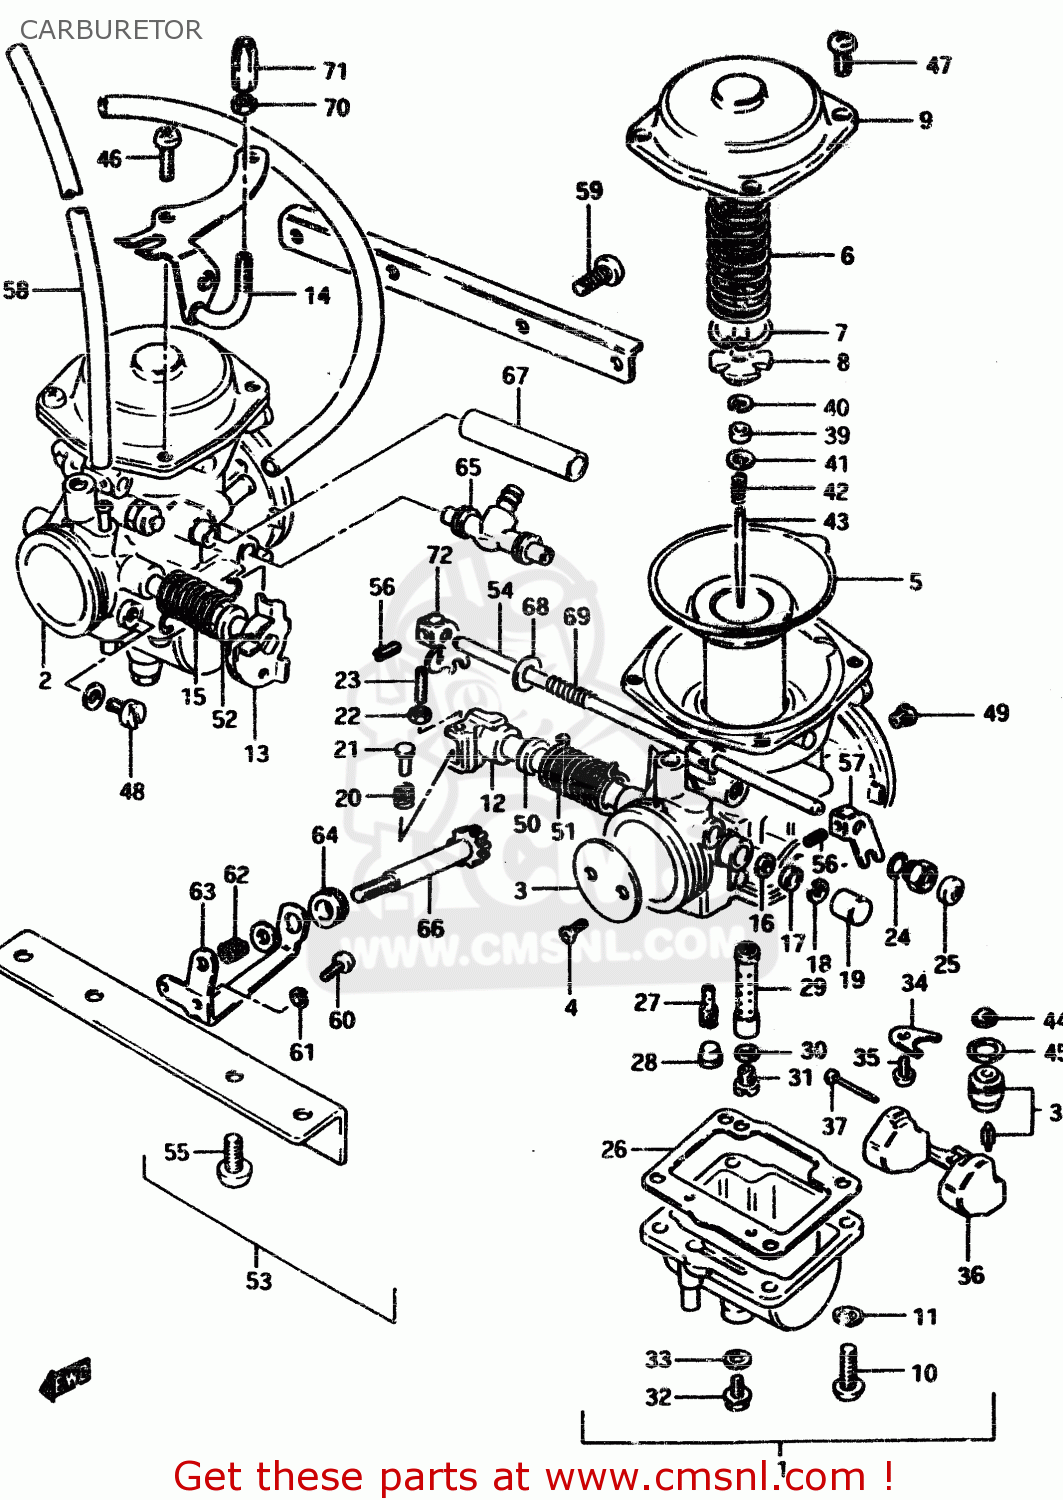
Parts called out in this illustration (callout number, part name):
1	CARBURETOR ASSY, LH
2	CARBURETOR ASSY, RH
3	VALVE, THROTTLE
4	SCREW
5	DIAPHRAGM ASSY
6	SPRING
7	E RING
8	HOLDER,GUIDE
9	COVER
10	SCREW
11	LOCK WASHER
12	SHAFT ASSEMBLY
13	SHAFT,THROTTLE
14	BRACKET,THROTTLE CABLE
15	SPRING
16	SEAL
17	GASKET,THROTTLE SHAFT (NAS)
18	E RING
19	CAP
20	SPRING,THROTTLE SCREW
21	PIN,THROTTLE LEVER
22	NUT
23	SCREW
24	O RING
25	CAP,STARTER VALVE
26	GASKET,FLOAT CHAMBER (NAS)
27	JET,PILOT(45)
28	PLUG,NEEDLE JET
29	JET, NEEDLE (0-9)
30	WASHER,NEEDLE NOZZLE
31	JET,MAIN(115)
32	PLUG,DRAIN
33	GASKET (NAS)
34	PLATE,NEEDLE VALVE FITING
35	SCREW 4X6
36	FLOAT
37	PIN,FLOAT
38	VALVE ASSEMBLY,NEEDLE
39	RING
40	CLIP
41	WASHER,JET NEEDLE
42	SPRING
43	NEEDLE, JET (5CDT61-3)
44	FILTER
45	O-RING,NEEDLE VALVE
46	SCREW
47	SCREW
48	SCREW
49	JET,AIR(140)
50	SPACER,THROTTLE SHAFT
51	SPRING
52	SPACER,THROTTLE SHAFT
53	FLANGE ASSEMBLY,CARBURETOR
54	SHAFT,STARTER
55	SCREW 6X12
56	SCREW
57	LEVER
58	HOSE
59	SCREW
60	SCREW
61	LOCK WASHER
62	SPRING,THROTTLE ADJUST
63	BRACKET
64	CAP,RUBBER
65	NIPPLE,CARBURETOR
66	SCREW
67	HOSE
68	WASHER,STARTER PLUNGER
69	SPRING,STARTER
70	NUT
71	ADJUSTER
72	LEVER,STARTER
